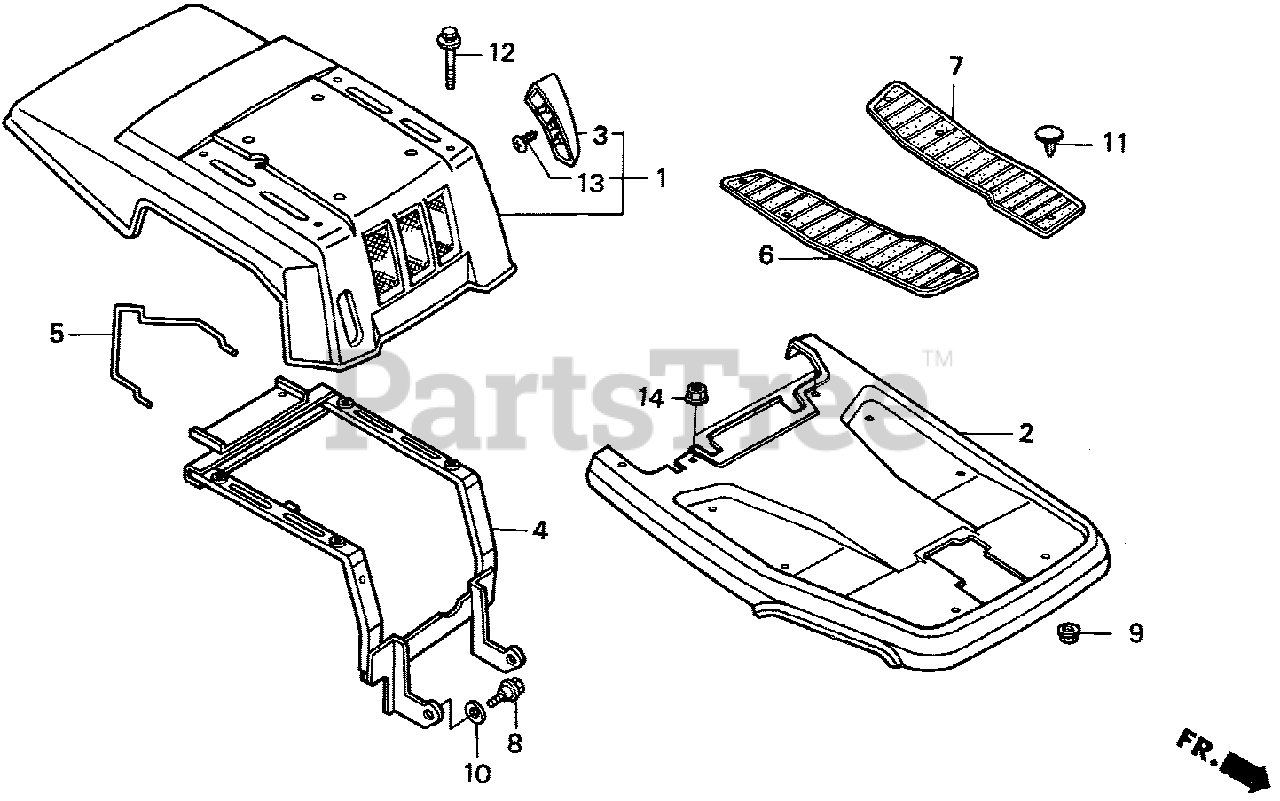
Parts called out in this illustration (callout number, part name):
1	BODY ASSY., RR. *R165* (JOLLY RED)
2	FLOOR *R280* (POWER RED)
3	INDICATOR, HEIGHT ADJUSTING *R165* (JOLLY RED)
4	FRAME, SEAT
5	SPRING, MANUAL SET
6	FLOOR MAT, R.
7	FLOOR MAT, L.
8	BOLT, HINGE (10MM)
9	NUT, FLANGE (6MM)
10	WASHER, LOCK (B)
11	CLIP, TRIM (BLACK)
12	BOLT-WASHER (6X20)
13	SCREW, TAPPING (5X10)
14	NUT, FLANGE (8MM)
